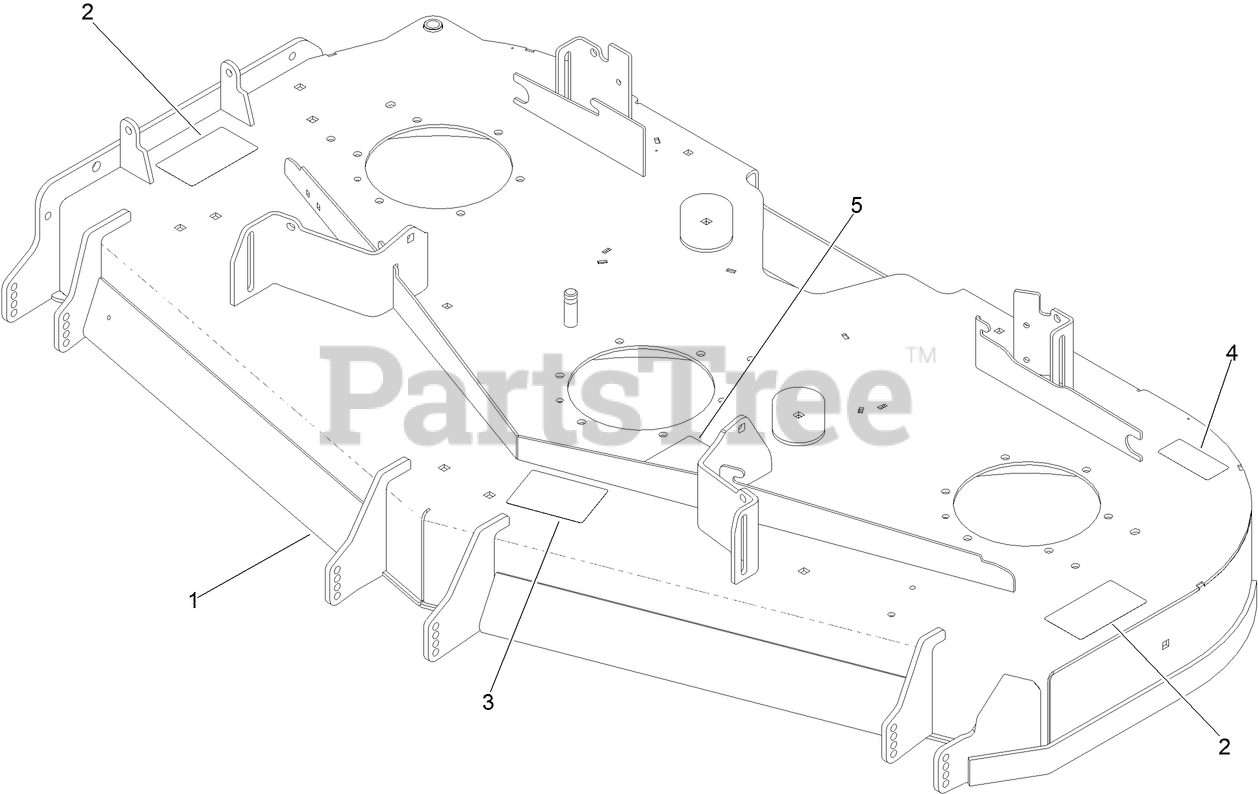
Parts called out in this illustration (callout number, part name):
1	Deck ASM W/Decals
2	DECAL-DANGER
3	DECAL-SCALP, ANTI
4	DECAL-BOLT TORQUE
5	DECAL-ROUTING, BELT
